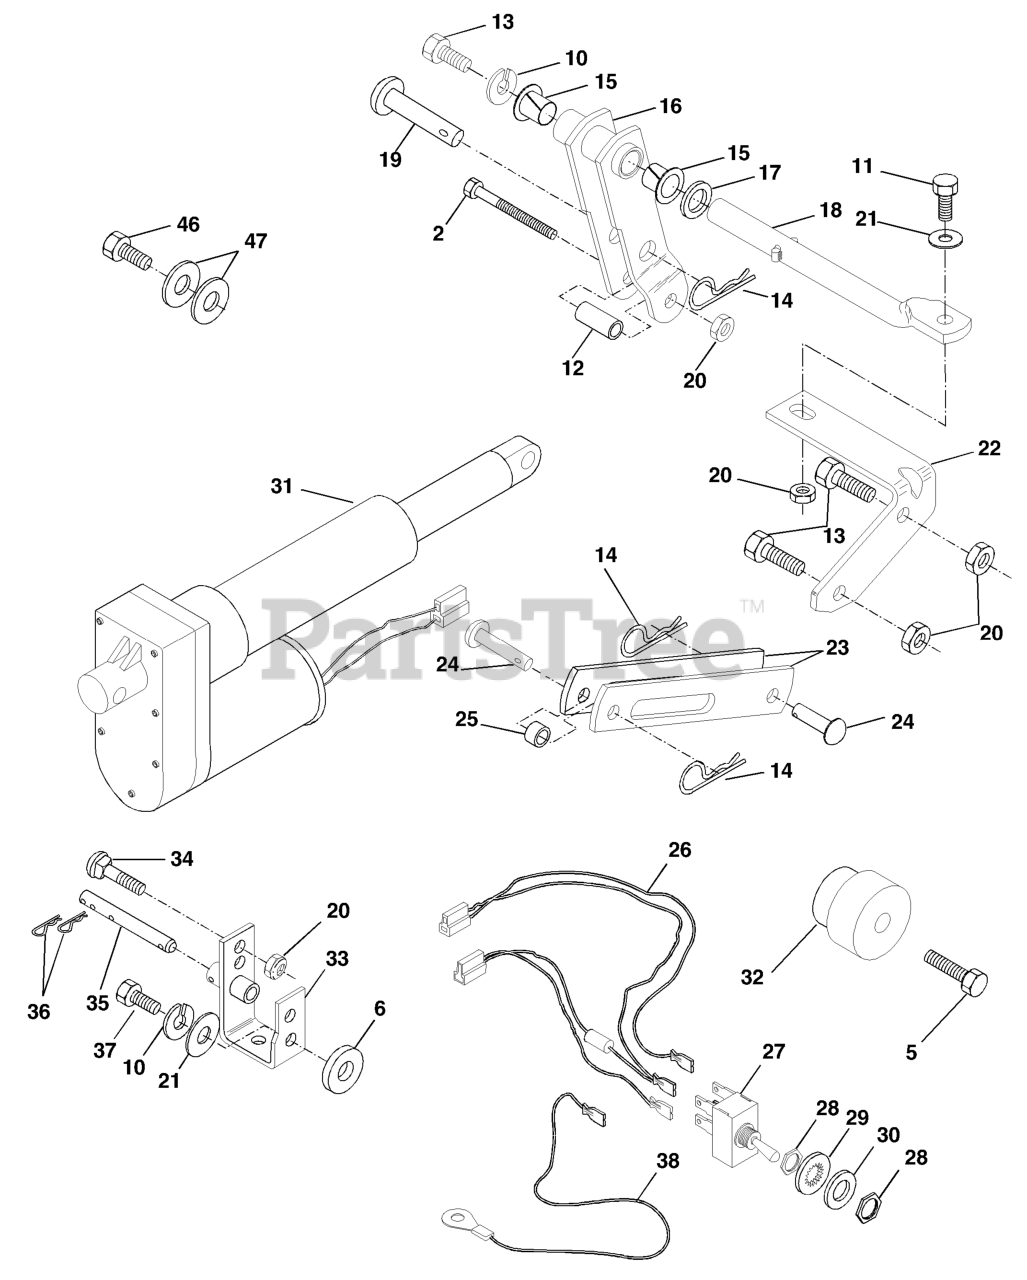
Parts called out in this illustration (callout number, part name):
2	Bolt, Hex 3/8-16 x 2-1/4 Grade 5
5	Bolt, Hex 3/8-16 x 1-3/8
6	Washer 13/32 x 7/8 x 7 Ga.
10	Washer, Lock
11	Bolt, Hex 3/8-16 x 1-1/4
12	Bushing .384 x 1/2 x 1-1/4
13	Bolt, Hex 3/8-16 x 7/8
14	Spring, Retainer
16	Arm, Pivot
17	Washer 21/32 x 1 x 21 Ga.
18	Rod, Pivot Support
19	Pin, Pivot
20	Locknut 3/8-16
21	Washer 13/32 x 7/8 x 16 Ga.
22	Bracket, Pivot Rod
23	Link, Lift
24	Pin, Pivot
25	Spacer
26	Harness, Lift Kit
27	Switch, Lift
28	Nut, Switch
29	Washer, Lock Int. Tooth
30	Washer 15/32 x 3/4 x 16 Ga.
31	Electric, Actuator
32A	Hub, Lever Lift (Splined)
32B	Hub, Lever Lift (Tapered)
33	Bracket Asm, Actuator, Gear Drive
34	Bolt, Carriage 3/8-16 x 1
35	Pin, Actuator
36	Spring, Retainer
37	Bolt, Hex 3/8-16 x 1
38	Wire, Ground
46	Screw 5/16-18 x 1-1/4
47	Washer 11/32 x 1-1/2 x 10 Ga.
